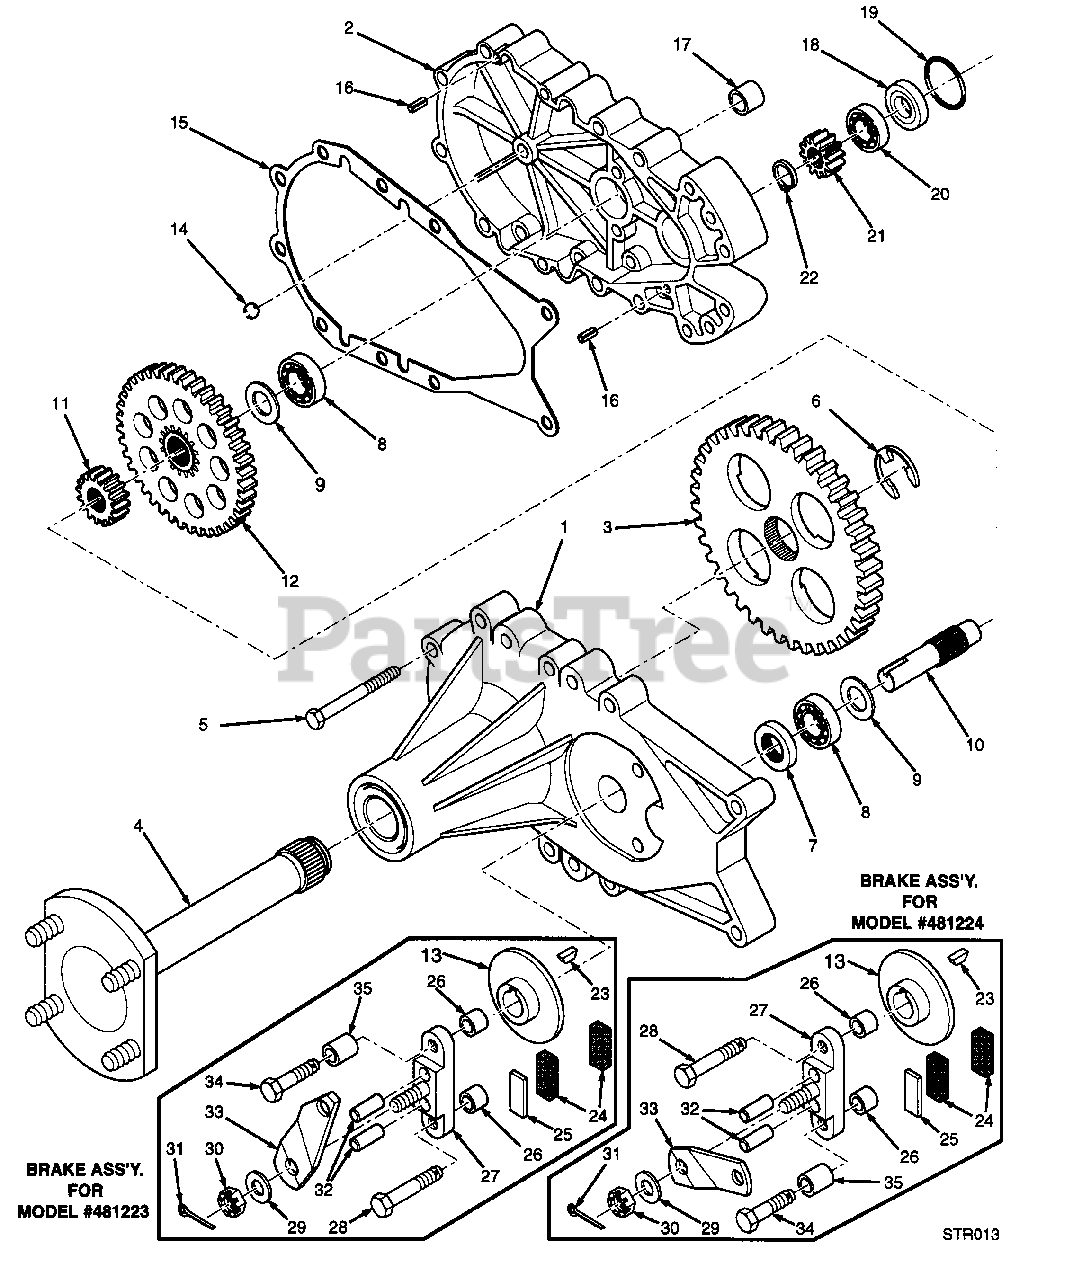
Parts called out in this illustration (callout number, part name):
1	AXLE HOUSING ASSEMBLY
2	HYDRO MOUNT HOUSING
3	SPLINED FINAL GEAR DRIVE
4	AXLE SHAFT ASSEMBLY
5	BOLT, 1/4-20 X 2-1/2 HEX HEAD
6	E-RING
9	WASHER, HT. 62ID X 1.0OD X .05 THICK
10	BRAKE SHAFT(SPLINED)
11	SPLINED REDUCTION GEAR, 17 TOOTH
12	SPLINED 60 TOOTH GEAR
13	DISC, BRAKE
14	BALL, 3/8 DIAMETER
15	GASKET, HOUSING
16	PIN, SPRING, 3/16 X 1/2 X 1/2 LONG
17	MOUNTING SPACER
18	BEARING, SPACER
19	O-RING
21	INPUT GEAR, 11 TOOTH
22	RETAINING RING
24	PUCK, BRAKE
25	PLATE, PUCK
26	BRAKE SPACER
27	BRAKE YOKE ASSEMBLY
28	BOLT, 1/4-20 X 1-1/2 HEX HEAD
29	WASHER, 7/16 X 7/8 OD X .06 HT
30	NUT, CASTLE, 5/16-24 PL
31	PIN, COTTER
32	PIN, BRAKE ACTUATING
33	ARM, BRAKE ACTUATOR(L.H. ASSEMBLY)
33	ARM, BRAKE ACTUATOR(R.H. ASSEMBLY)
34	BOLT, 1/4-20 X 2-1/2 HEX HEAD
35	SPACER
